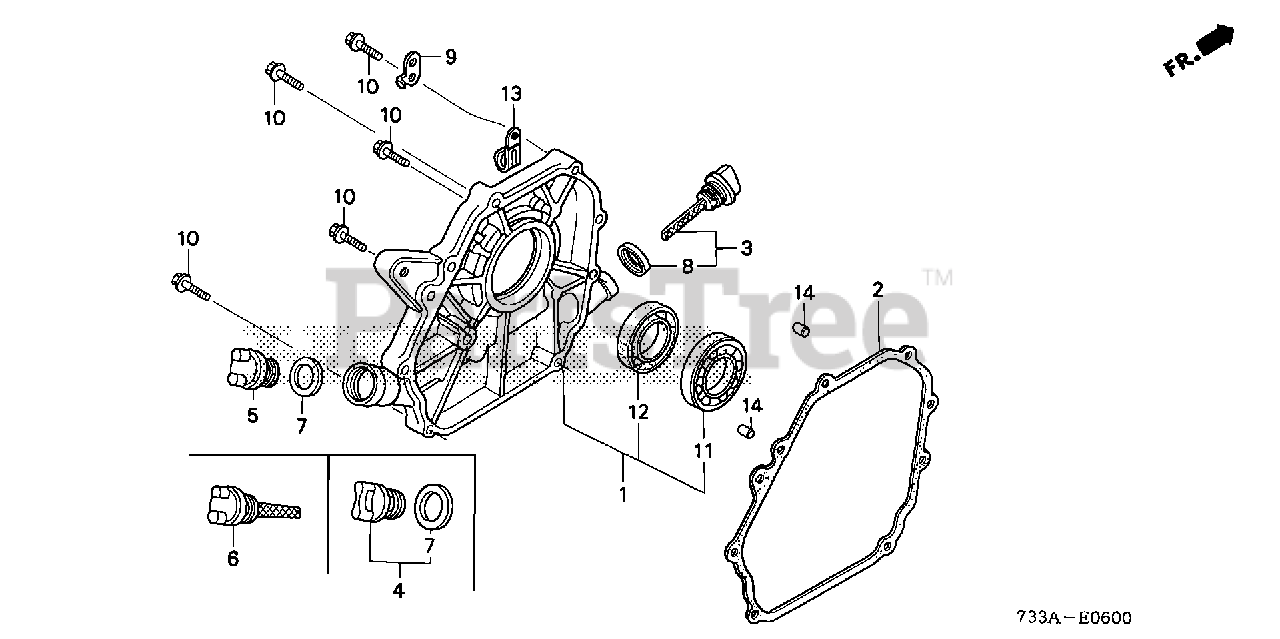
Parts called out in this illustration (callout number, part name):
1	COVER ASSY., CRANKCASE
2	GASKET, CASE COVER (NON-ASBESTOS)
3	CAP ASSY., OIL FILLER (GRAY)
4	CAP ASSY., OIL FILLER
5	CAP, OIL FILLER
7	GASKET, OIL FILLER CAP
8	GASKET, OIL FILLER CAP
9	STAY, WIRE CLIP (A)
10	BOLT, FLANGE (8X32)
11	BEARING, RADIAL BALL (6205)
12	OIL SEAL (25X41X6)
14	PIN, DOWEL (8X14)
